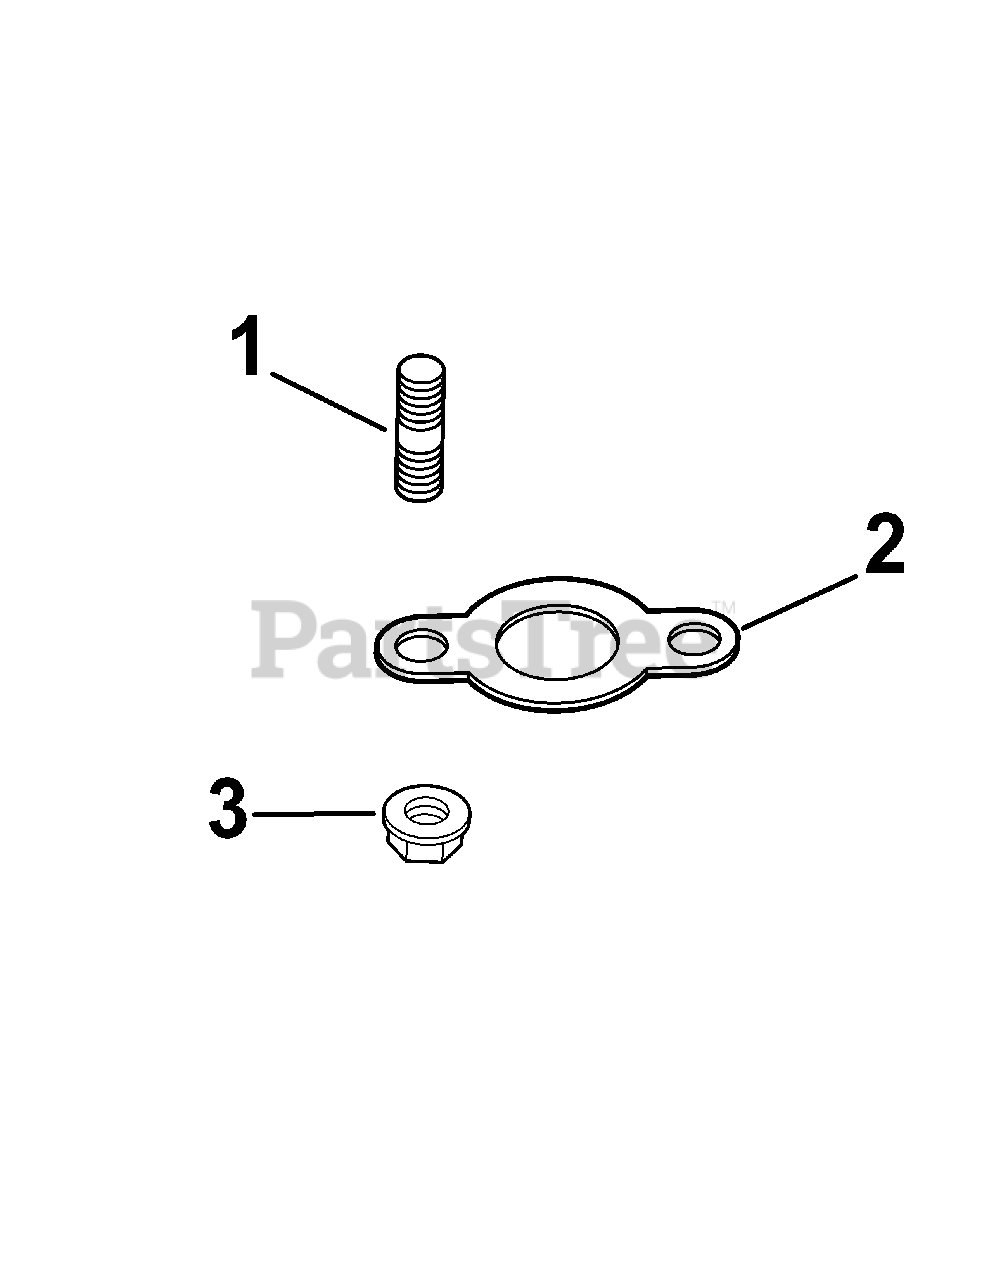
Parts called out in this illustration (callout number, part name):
1	Stud M8x1.25x33 (4) (Exhaust)
2	Gasket, exhaust manifold
3	Nut, hex. flange M8x1.25 (5)
